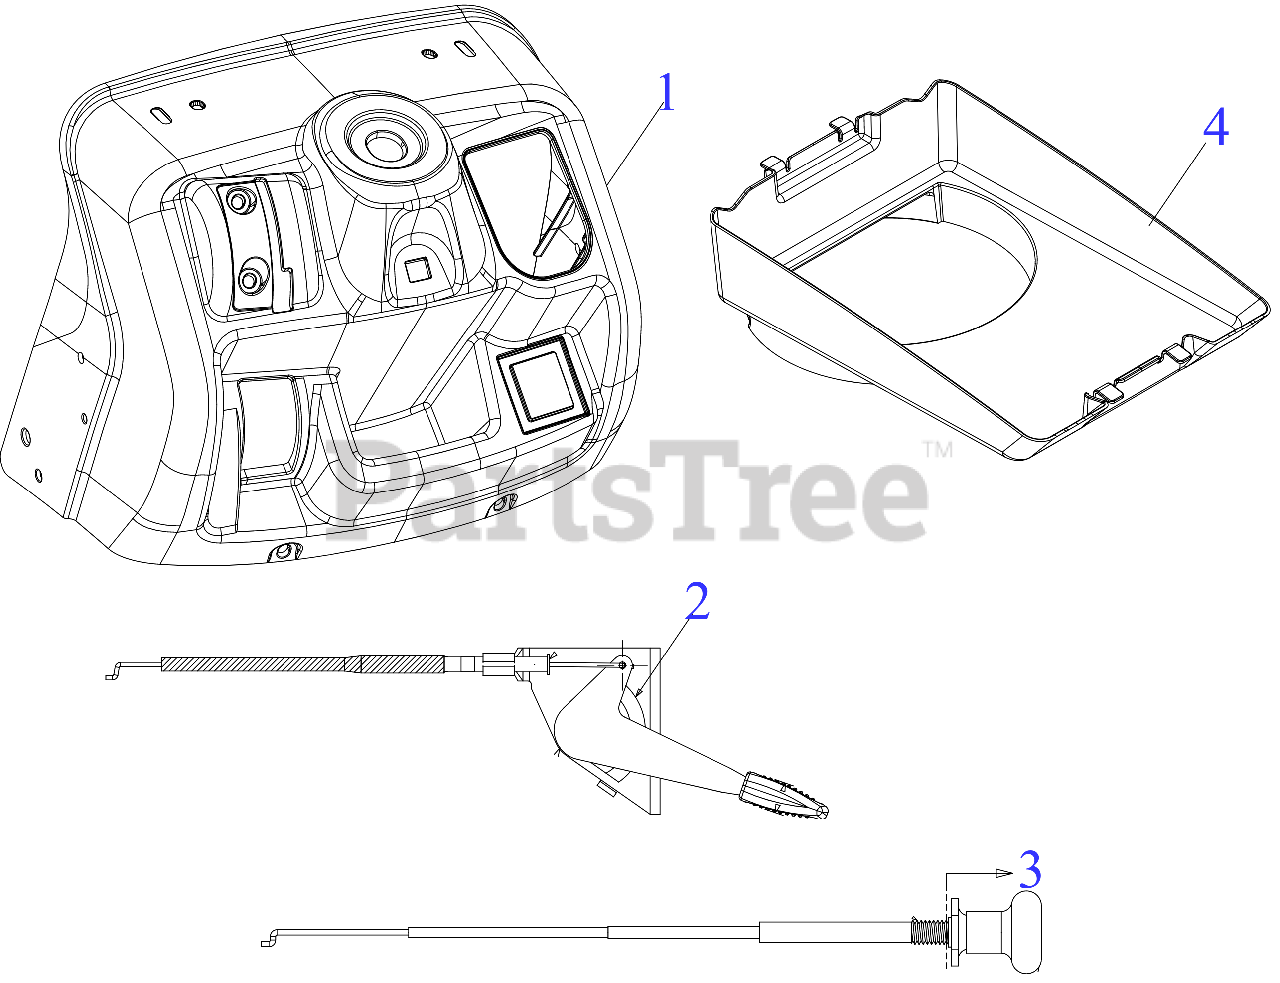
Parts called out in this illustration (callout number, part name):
2	THROTTLE CABLE 41.5 x .62
3	40.5" CHOKE CABLE
4	HOOD PLENUM
